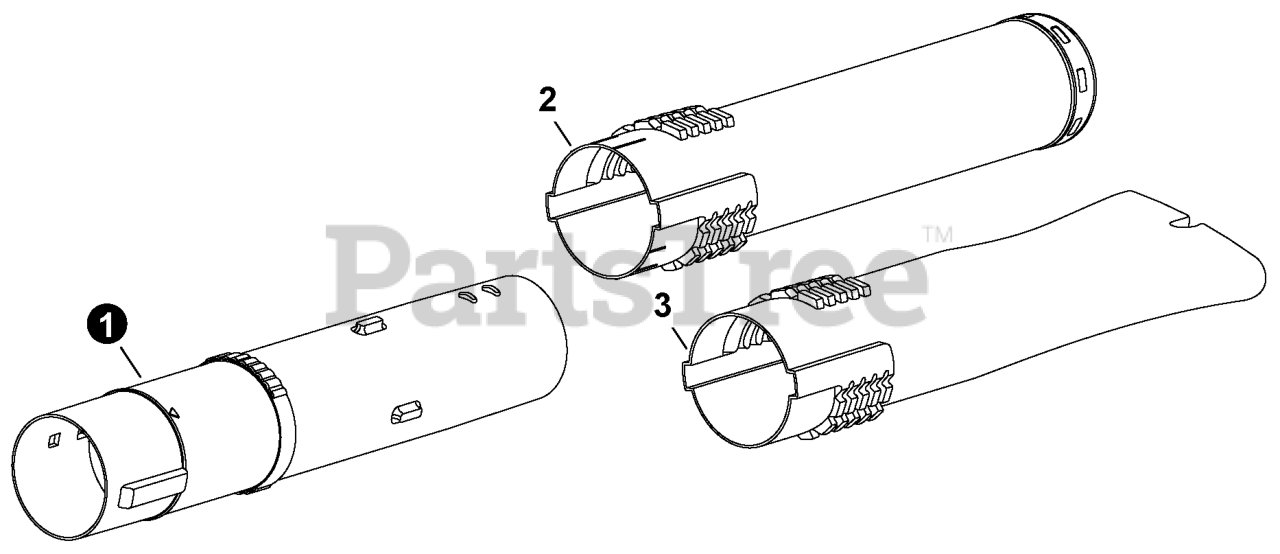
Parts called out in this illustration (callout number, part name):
1	TUBE, BLOWER - STRAIGHT
2	TUBE, BLOWER - NOZZLE
3	TUBE, BLOWER - FLARED NOZZLE
